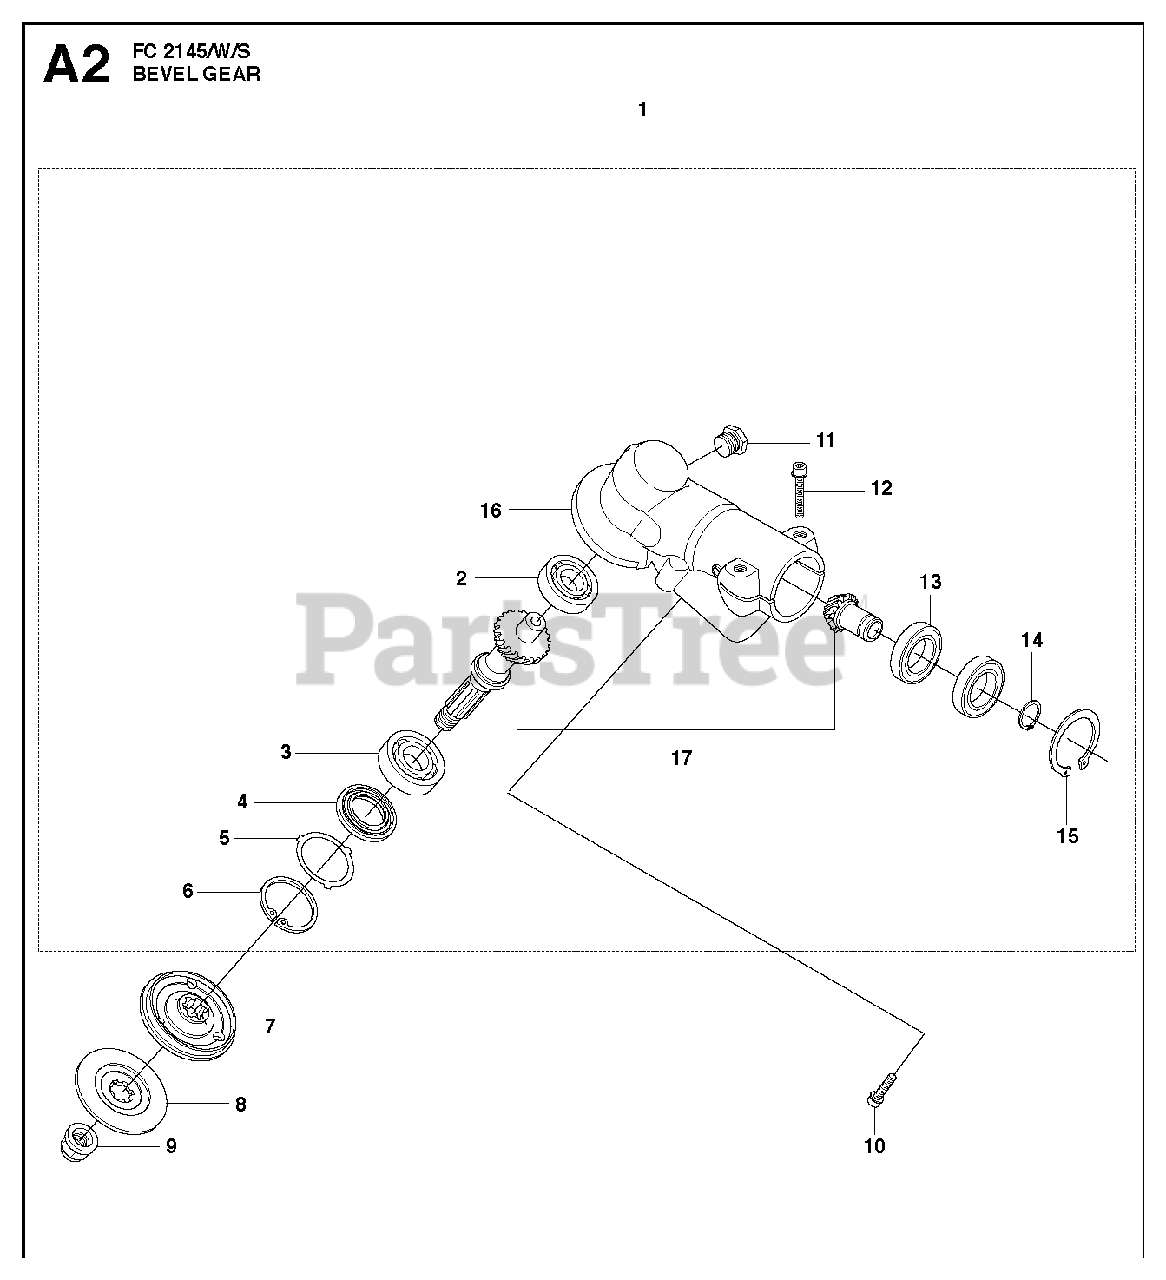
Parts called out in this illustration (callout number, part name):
1	GEAR HOUSING ASSY
2	BALL BEARING
3	BALL BEARING
4	SEAL
5	WASHER
6	RETAINING RING SGH 35
7	DRIVER
8	SUPPORT FLANGE
9	NUT BLADE
11	PLUG
12	SCREW
13	BALL BEARING
14	RETAINING RING SGA 15
15	RETAINING RING
16	GEAR HOUSING
17	SPARE PARTS KIT
